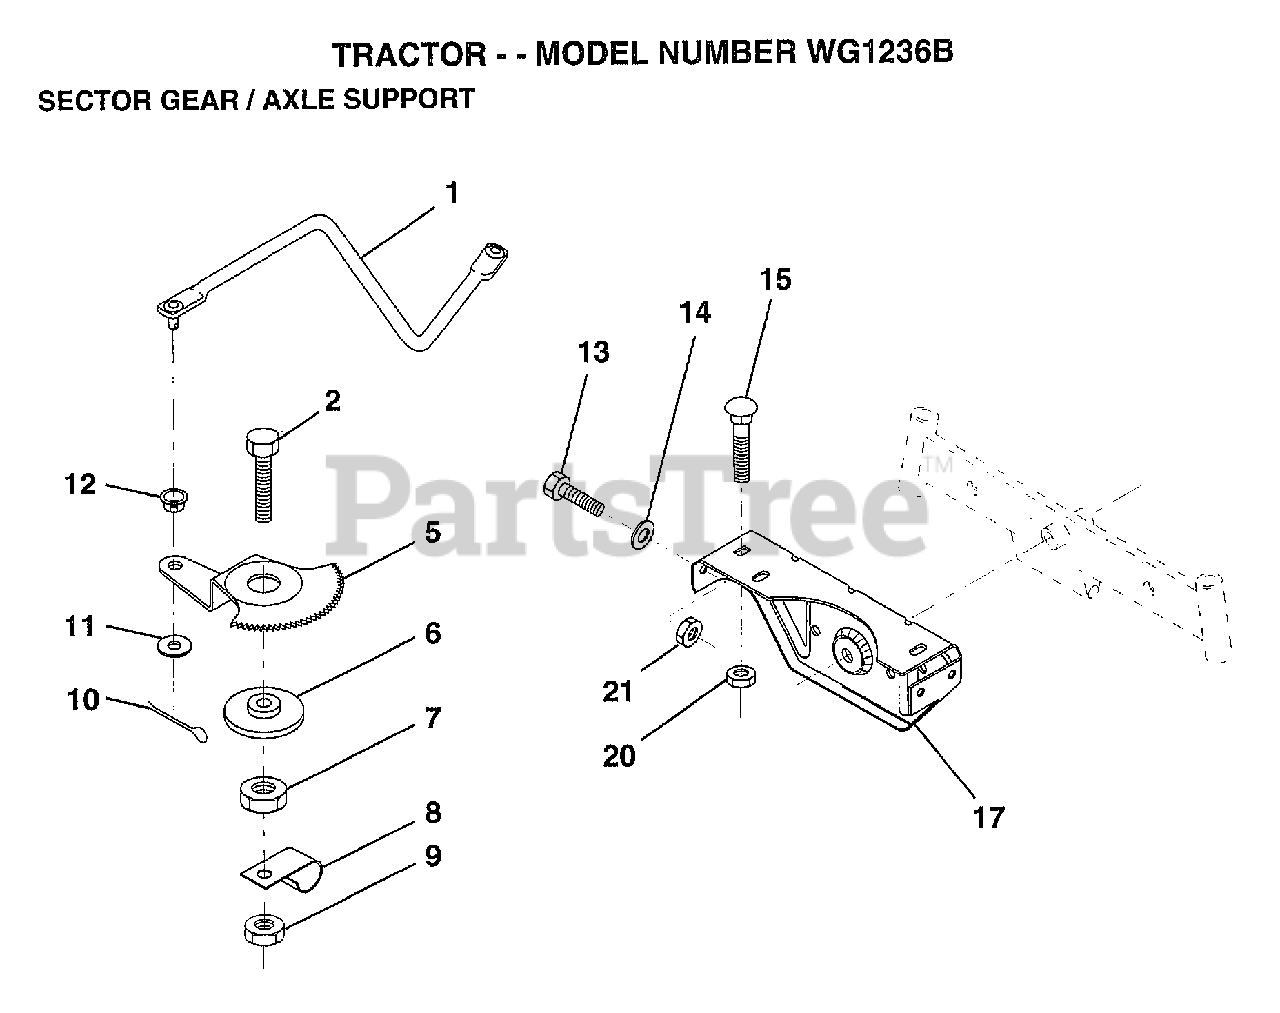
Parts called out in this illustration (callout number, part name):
1	DRAG LINK
2	"BOLT,HEX"
5	GEAR SECTOR
6	BUSHING
7	NUT
8	CLIP INSULATOR
9	NUT LTV
10	COTTER PIN
11	WASHER
12	BUSHING.DRAGLINK
13	BOLT
14	WASHER
15	BOLT
17	SUPT AXLE FRONT
